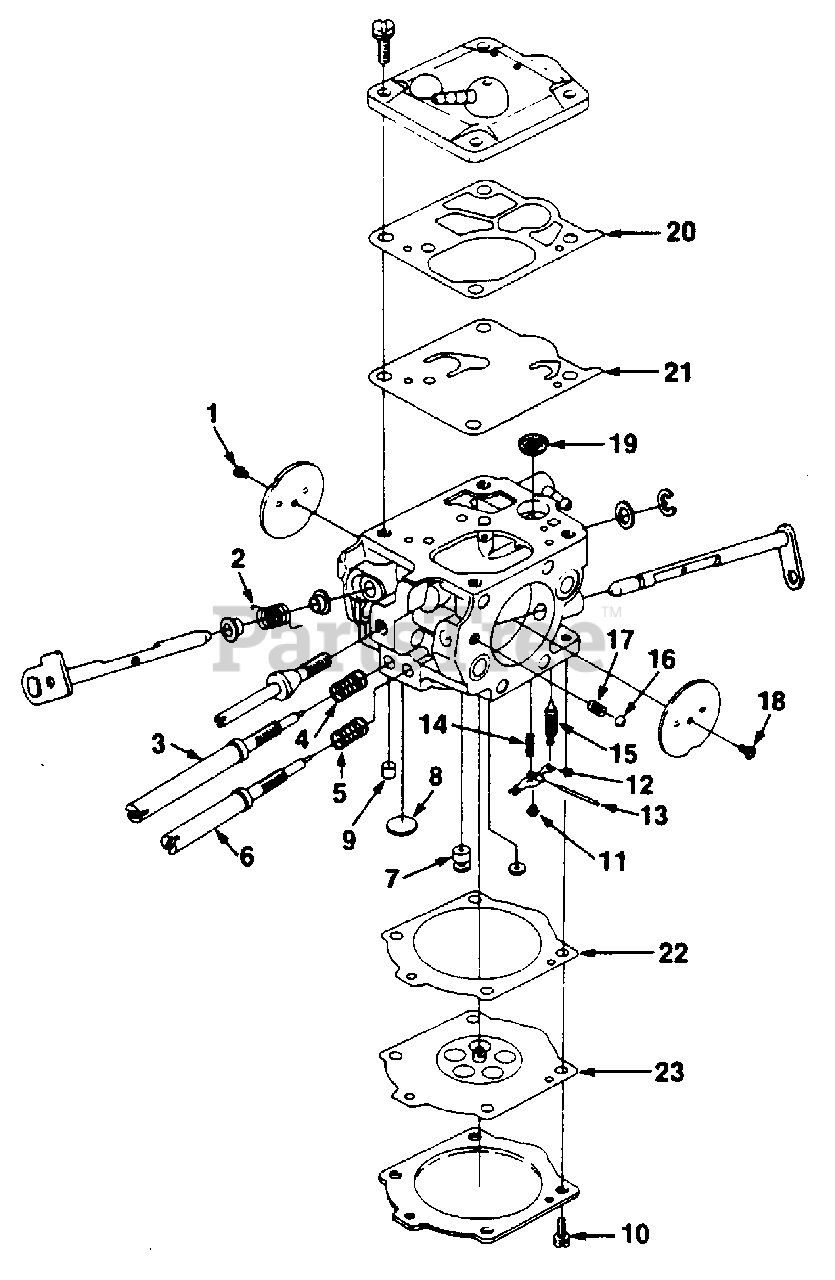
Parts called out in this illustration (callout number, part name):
1	REPAIR KIT
2	REPAIR KIT
3	REPAIR KIT
4	REPAIR KIT
5	REPAIR KIT
6	REPAIR KIT
7	REPAIR KIT
8	REPAIR KIT
9	REPAIR KIT
10	REPAIR KIT
11	REPAIR KIT
12	REPAIR KIT
13	REPAIR KIT
14	REPAIR KIT
15	REPAIR KIT
16	REPAIR KIT
17	REPAIR KIT
18	REPAIR KIT
19	REPAIR KIT
20	REPAIR KIT
21	REPAIR KIT
22	REPAIR KIT
23	REPAIR KIT
